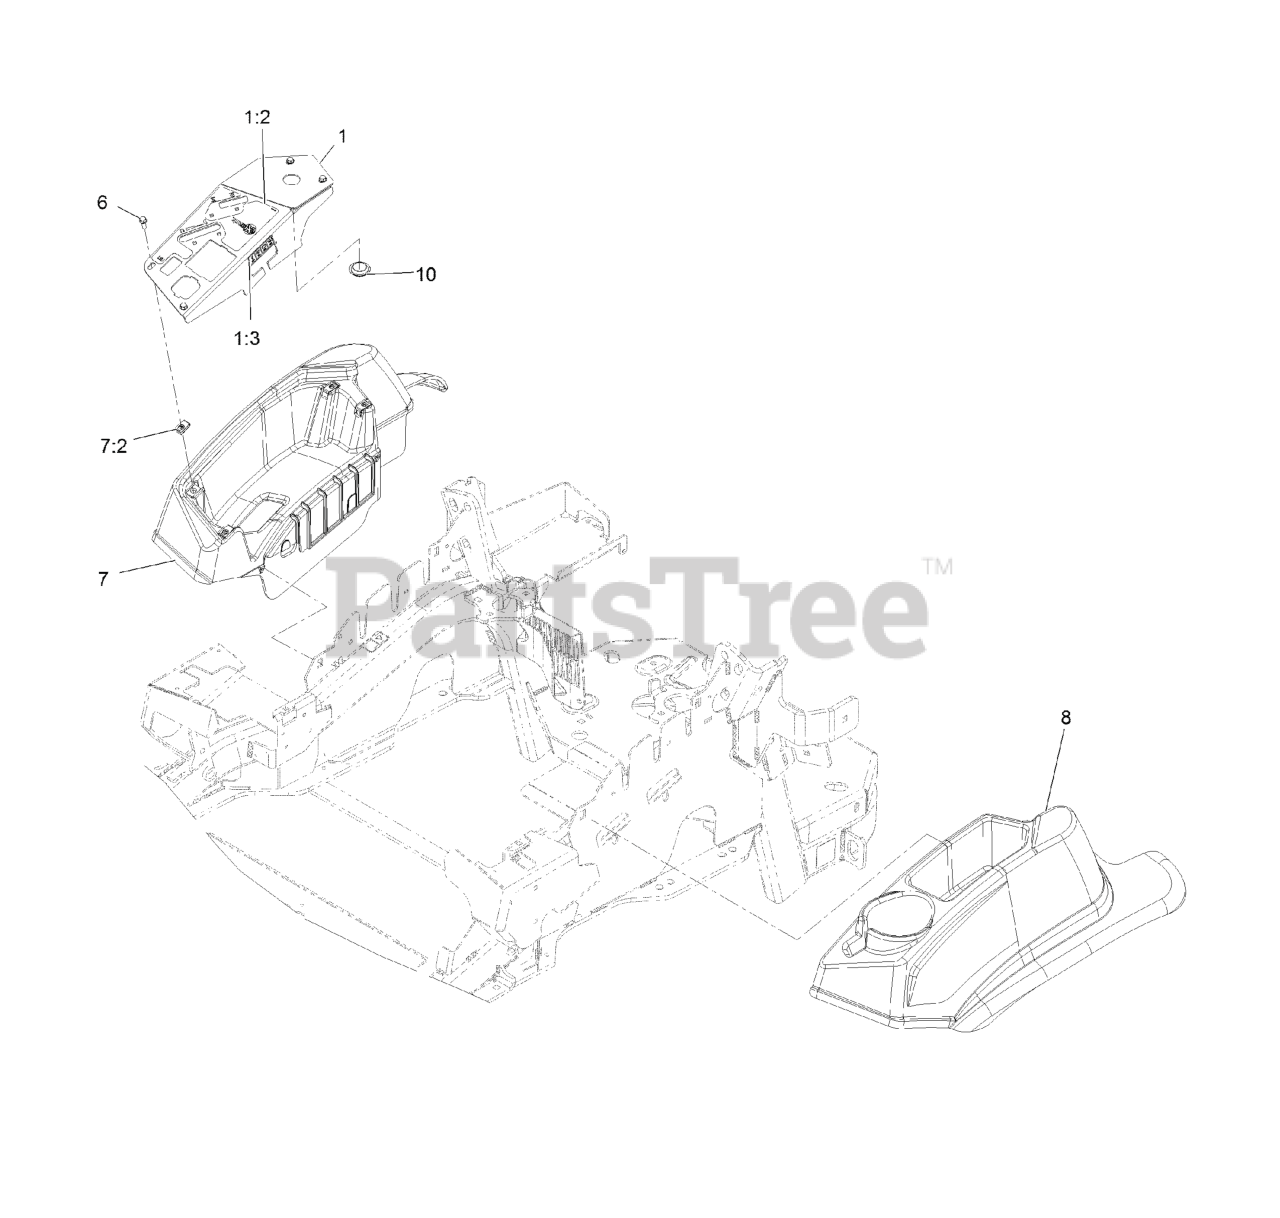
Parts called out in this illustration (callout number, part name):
1	ASM,CONSOLE PANEL W/DECAL
1:2	DECAL-CONTROL PANEL NON-EFI
1:3	DECAL-FUSES
6	SCREW-HWH
7	CONSOLE,RH AS ASM
8	CONSOLE, LH AS
10	PLUG-PLASTIC
